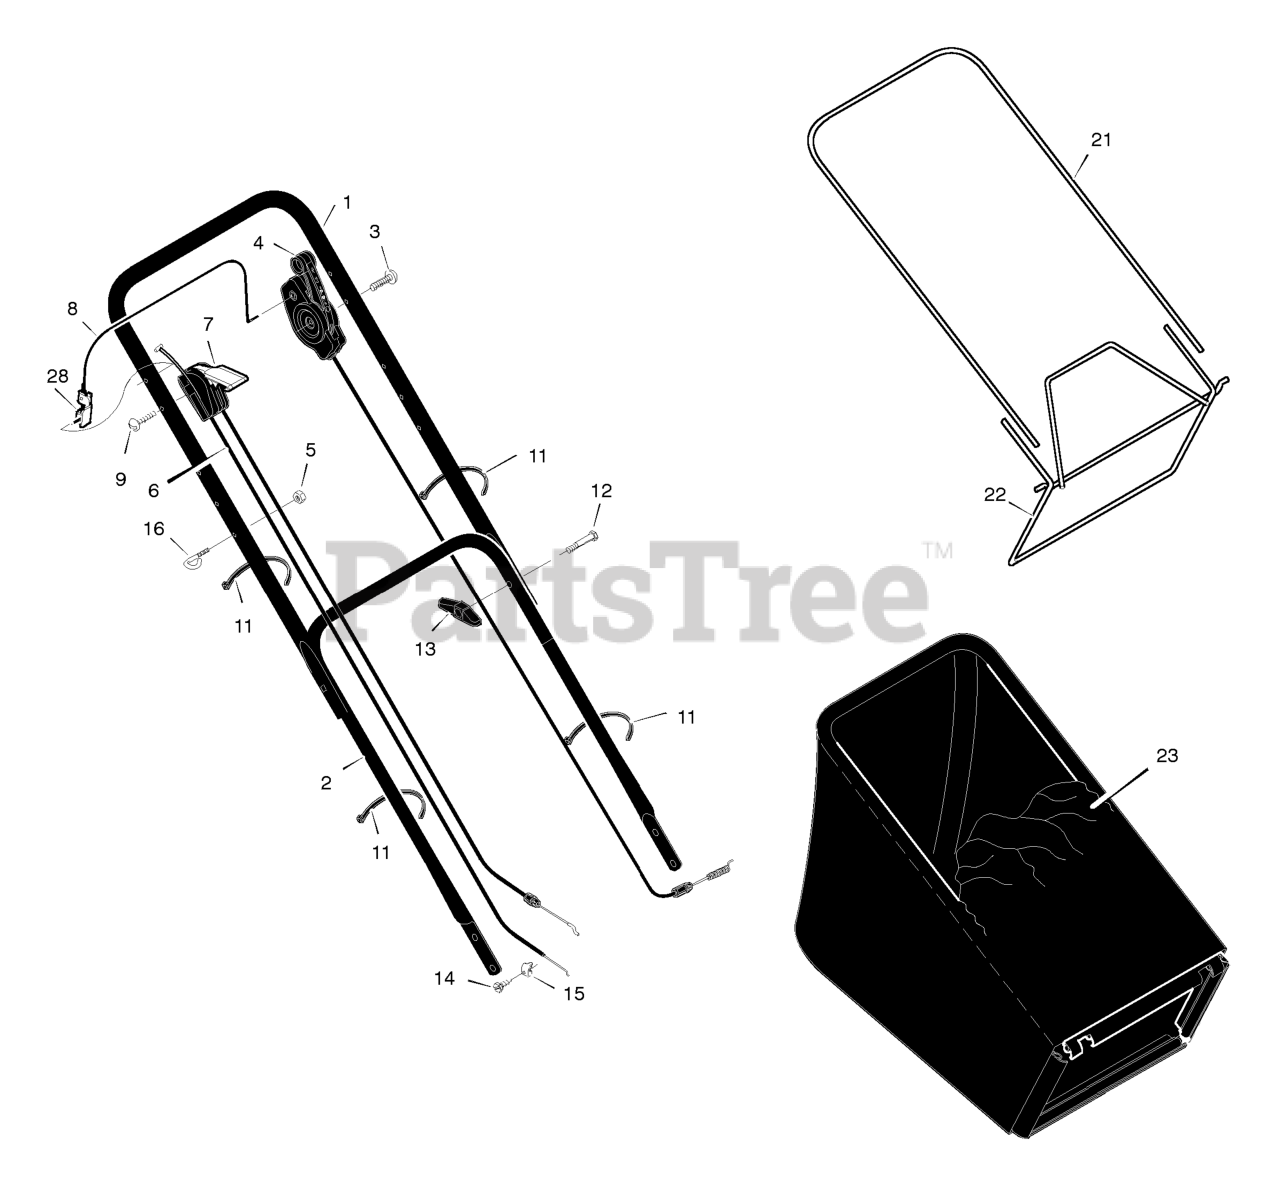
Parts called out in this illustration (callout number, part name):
1	Handle, Upper
2	Handle, Lower
4	Control, Drive
5	Locknut
6	Cable, Stop
7	Throttle Control
8	Engine Stop Lever
11	Fastener, Cable
13	Knob
16	Guide, Rope
21	Frame, Top
22	Frame Assembly
23	Bag, Cloth
28	Bracket, Stop Lever
